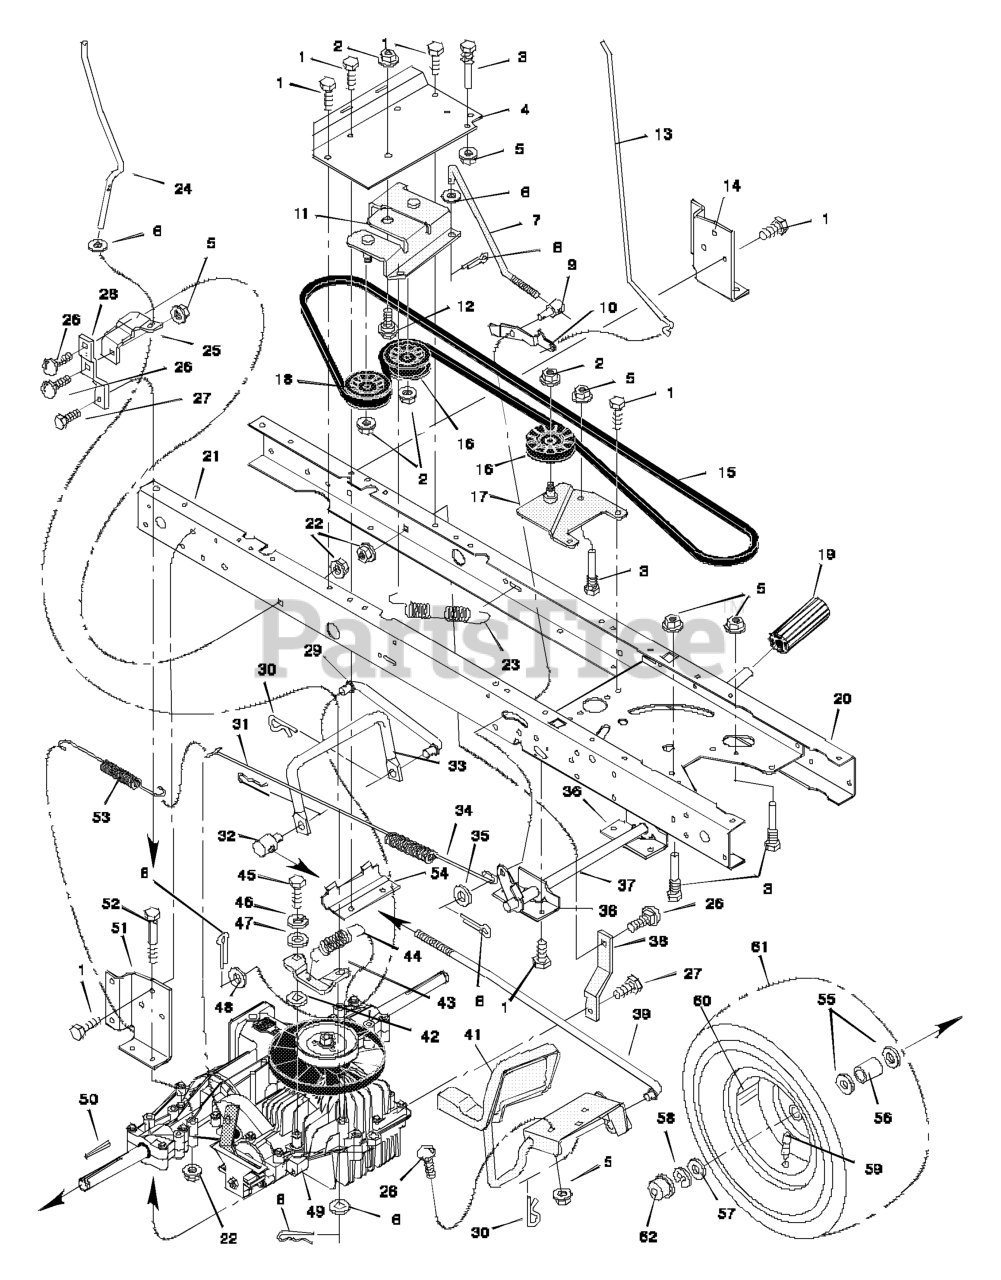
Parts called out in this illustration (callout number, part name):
2	Nut, Flange
3	Guide, Belt
4	Bracket, Idler
5	Locknut
6	Washer
7	Rod, Clutch
8	Pin, Cotter
9	Adjuster
10	Latch, Parking Brake
11	Bracket Assembly, Idler
12	Bolt, Shoulder
13	Rod, Parking Brake
14	Bracket, Transaxle
16	Pulley, Idler
17	Arm Assembly, Idler
18	Pulley, Idler
19	Pedal
20	Frame, Left
21	Frame, Right
22	Nut, Flange
23	Spring, Extension
24	Rod, Disconnect
25	Bracket, Disconnect
26	Bolt, Carriage
28	Strap, Right Torque
29	Rod, Link
30	Pin, Hair
31	Pin, Hair
32	NUT, Adjusting, 1/2-13
33	Rod, Yoke
34	Spring, Extension
35	Washer
36	Bracket, Pivot
37	Lever, Clutch/Brake
38	BRACKET, Torque Strap, LH
39	Rod, Link
41	Pedal, Speed Control
43	Arm, Disconnect
44	Spring
46	Lockwasher
48	Washer
49	Transaxle **
50	Key, Square
51	Bracket, Right Transaxle
52	Bolt
53	Spring, Extension
54	Clamp, Transaxle
56	Spacer
58	E- Ring
59	Valve Stem
60	Wheel & Tire Assembly
62	Cap, Hub
